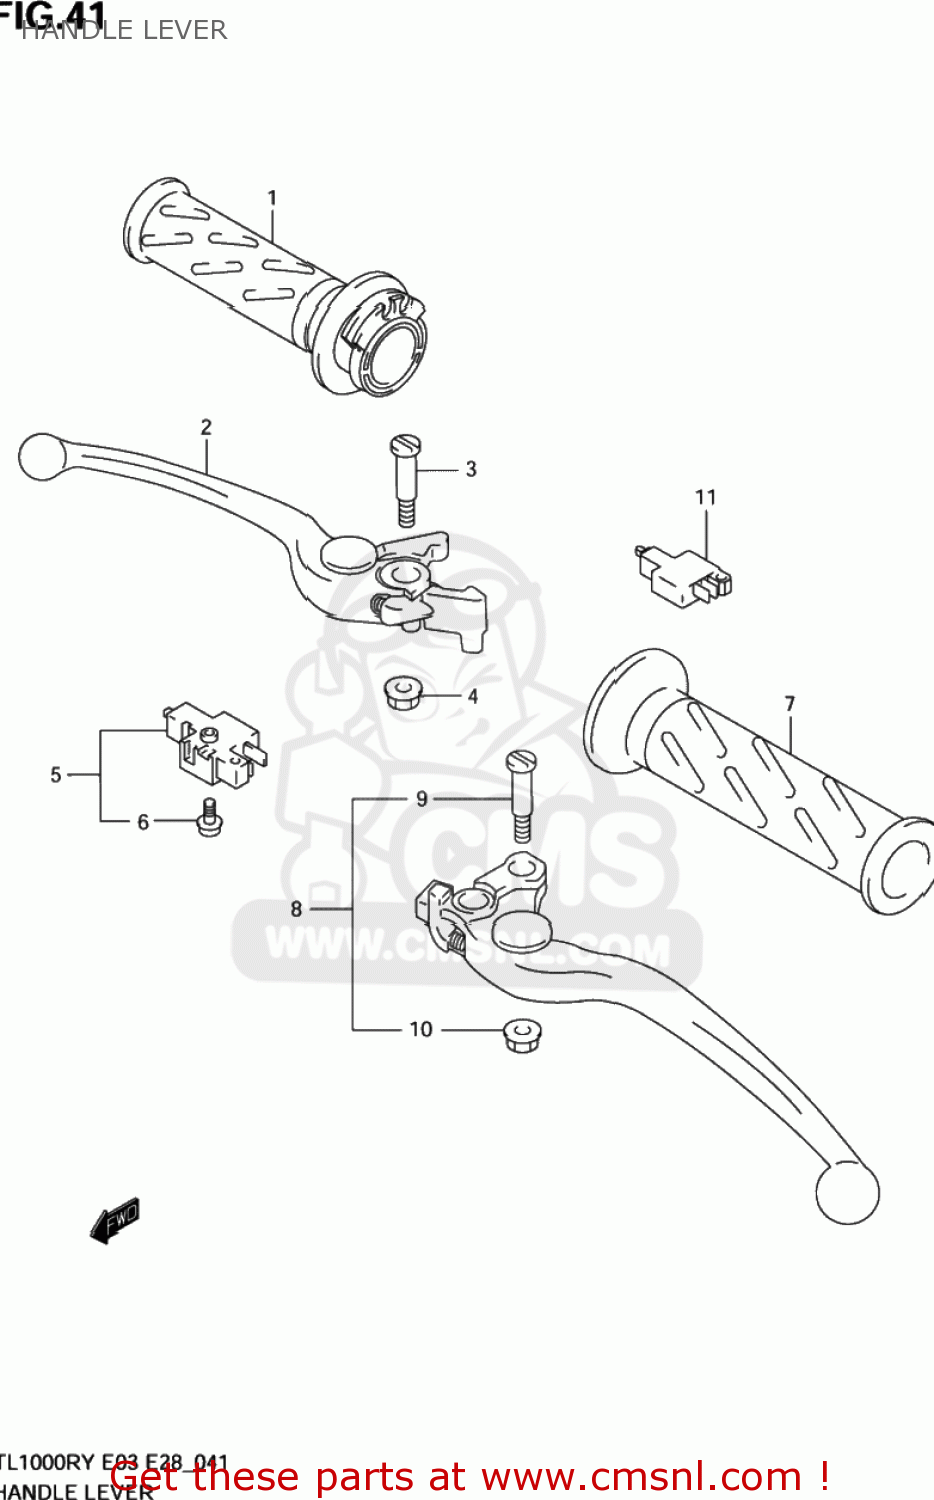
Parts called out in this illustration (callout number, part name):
1	GRIP,THROTTLE
2	LEVER ASSY,ADJUST
3	BOLT,LEVER PIVOT
4	NUT
5	SWITCH ASSEMBLY,STOP
6	SCREW
7	GRIP,LEFT
8	LEVER ASSY,CLUTCH
9	BOLT,LEVER PIVOT
10	NUT
11	SWITCH ASSY,CLUTCH
